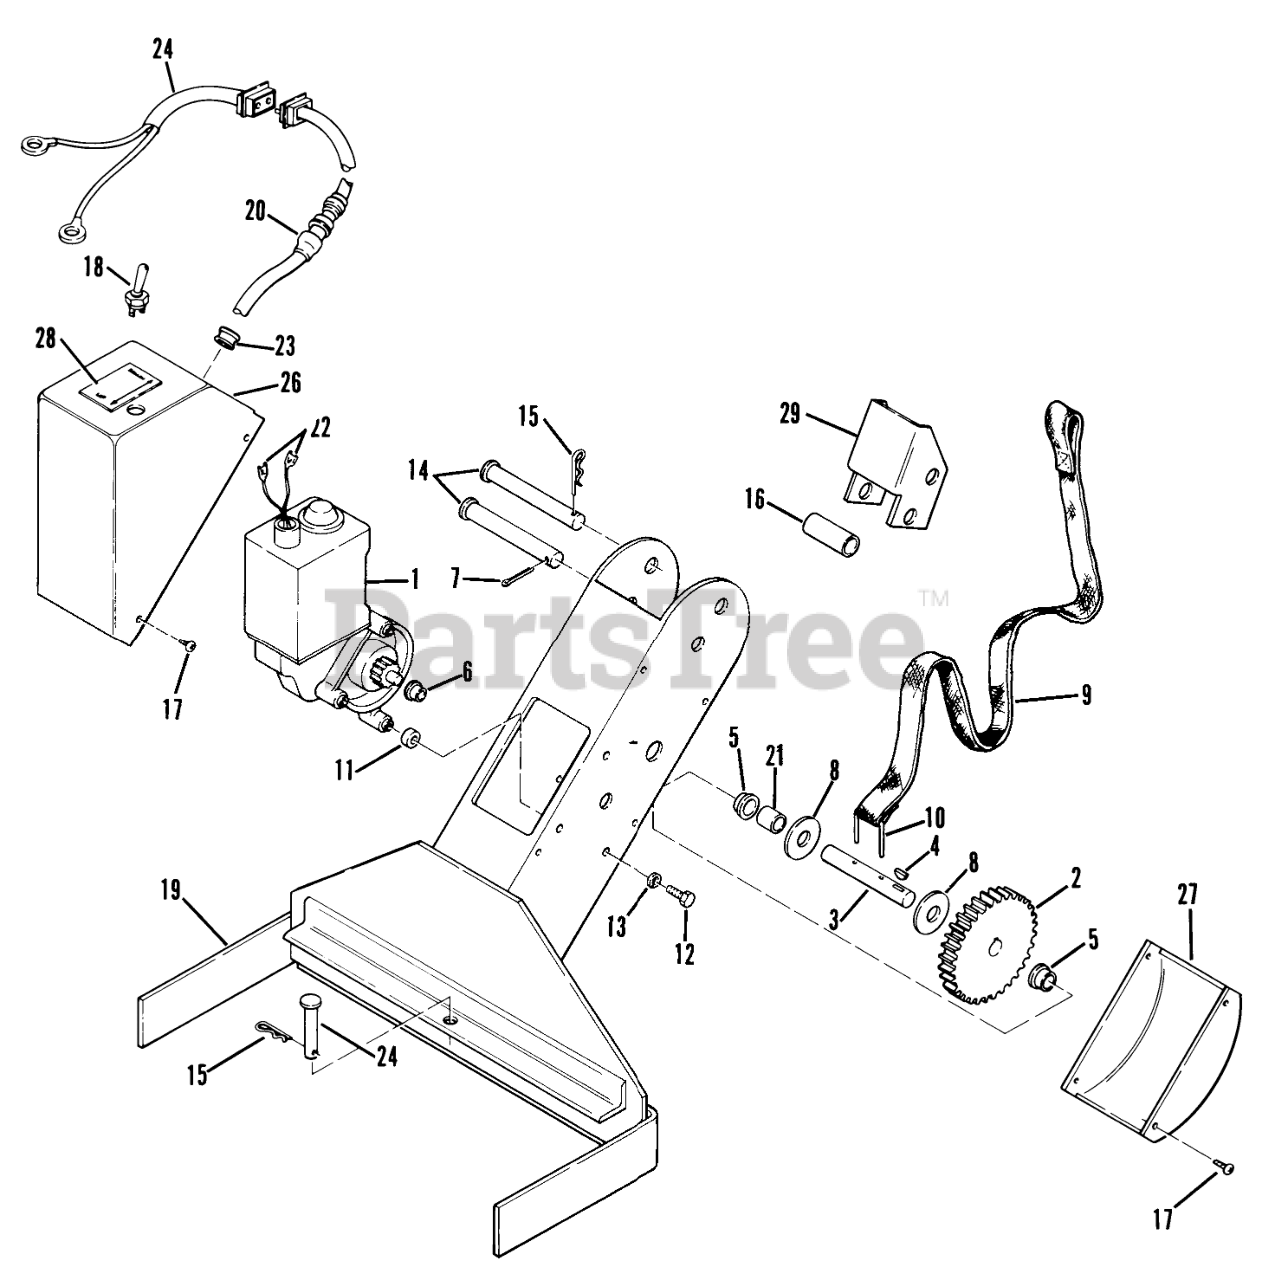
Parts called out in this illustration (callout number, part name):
1	Motor
3	Shaft
4	Woodruff Key #3
5	Bearing, Flgd.
6	Flanged Bearing
7	Cotter Pin .109 x 1
8	Washer, STD. 5/8
9	Lift Strap
11	Spacer
12	Hex Bolt 1/4-20 x 7/8
13	Lockwasher 1/4
14	Clevis Pin
15	Hairpin Cotter
16	Sleeve
17	Self Tapping Screw
18	Switch
19	Frame Assembly
20	Power Cord
21	Spacer
22	Jumper Wire
23	Strain Relief Bushing
24	Clevis Pin
25	Power Cord To Battery
26	Motor Cover
27	Gear Cover
28	Decal
29	Chain Bracket
29	Fuse (FU-2)
